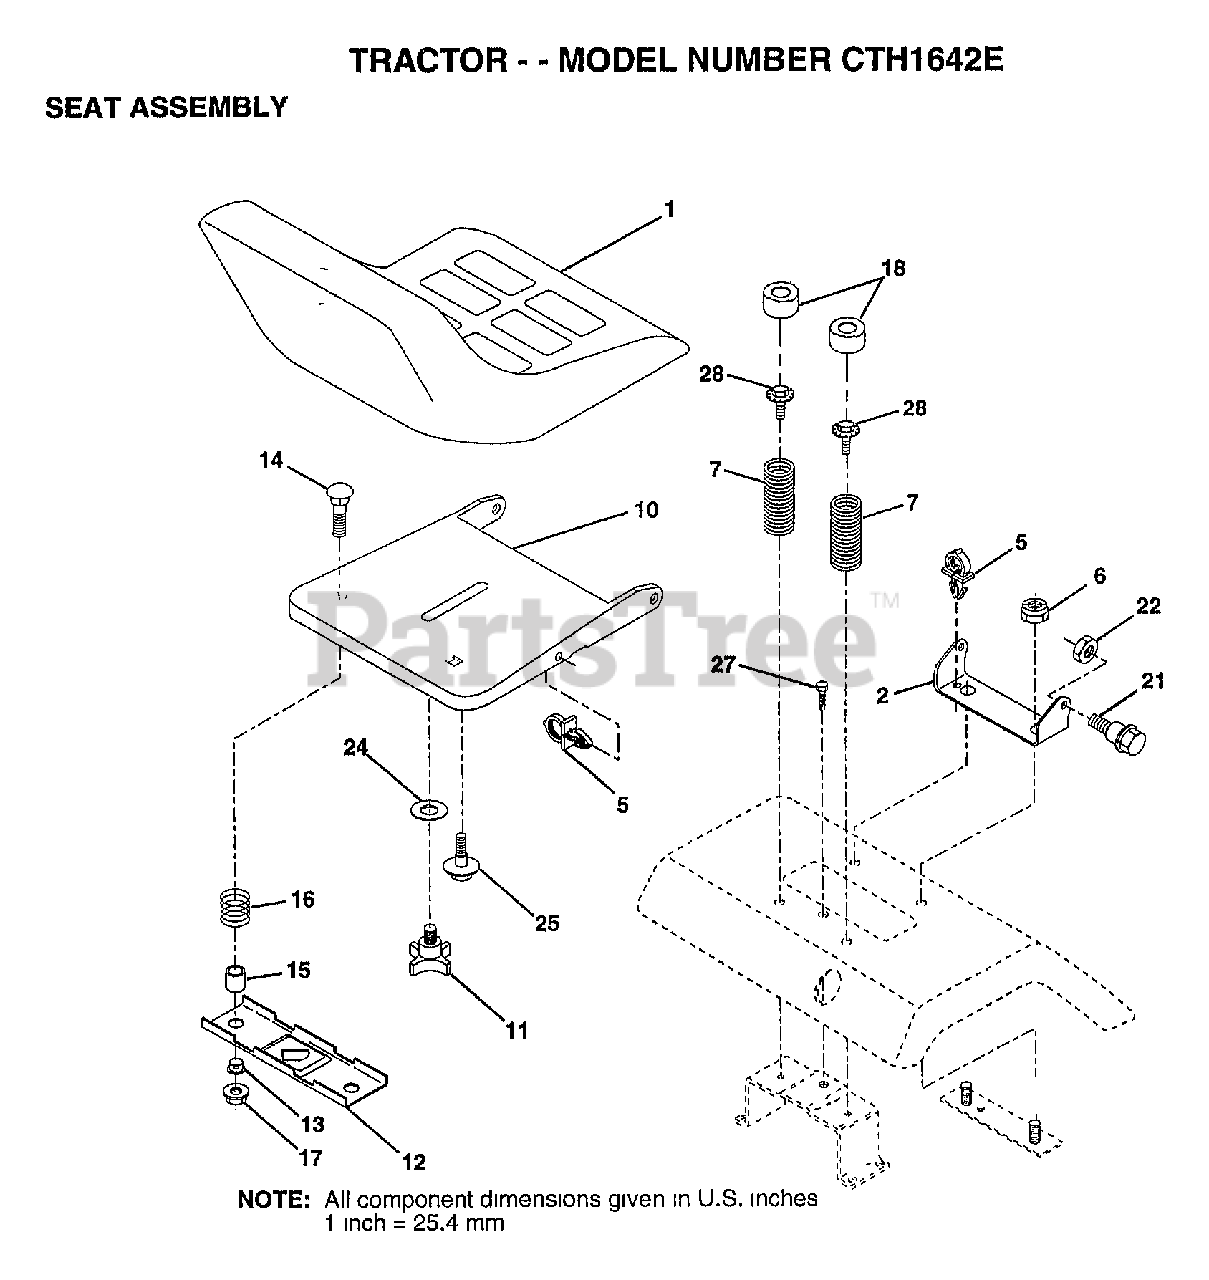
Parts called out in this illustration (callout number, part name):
2	BRACKET PVT SEAT
5	CLIP.PUSH-IN.HING
6	NUT
7	SPRING COMPRESSIO
10	PAN-SEAT
11	"KNOB 1/2"" YT"
12	BRKT SWITCH
13	BUSHING
15	SPACER SPLIT
16	SPRING COMPRESSED
18	CAP SPRING
21	"BOLT,SHOULDER"
24	WASHER
25	"BOLT,SHOULDER"
27	SCREW LT
28	BOLT.5/16-18.UNC
